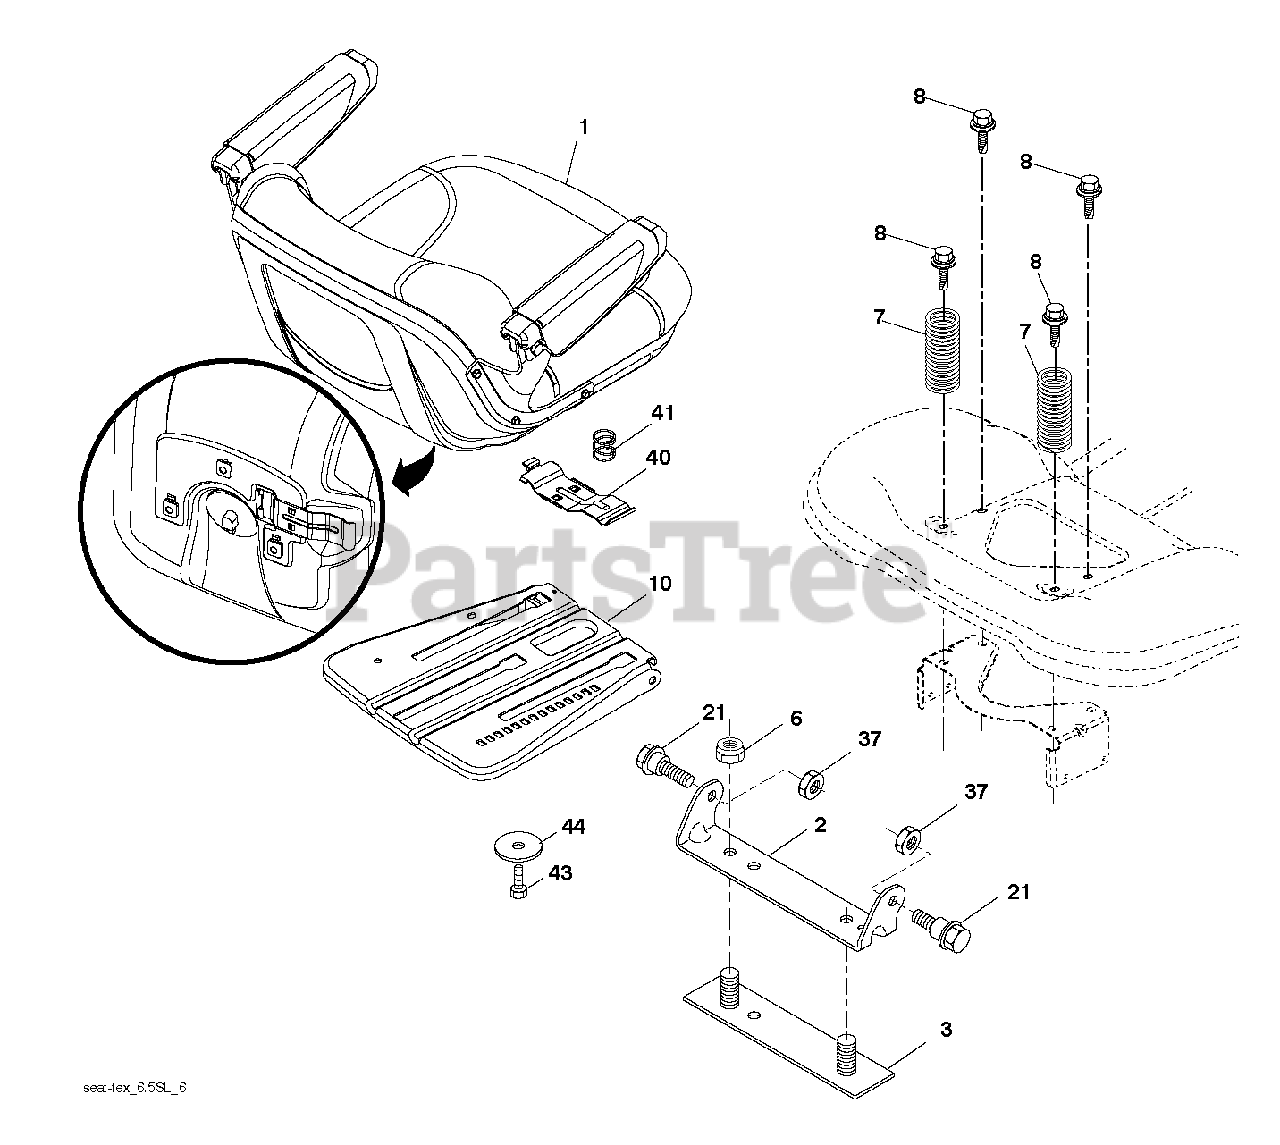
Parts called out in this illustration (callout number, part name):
1	SEAT.TH154.GREY.HUS.ARMREST
2	BRKT.PIVOT.FENDER
3	STRAP
6	NUT
7	SPRING.COMPRESSION.SEAT.BLACK
8	BOLT, 5/16-18 X 1 3/4
10	PAN.ASM.SEAT.3PT
21	BOLT.SHOULDER.5/16-18
37	NUT.71038.31-18.HEX.NYLOCK
40	HANDLE.SLIDE.SEAT.TEX.BLACK
41	SPRING.LATCH.SEAT.TEX
44	WASHER 13/32 X 2-3/8 X 12GA
